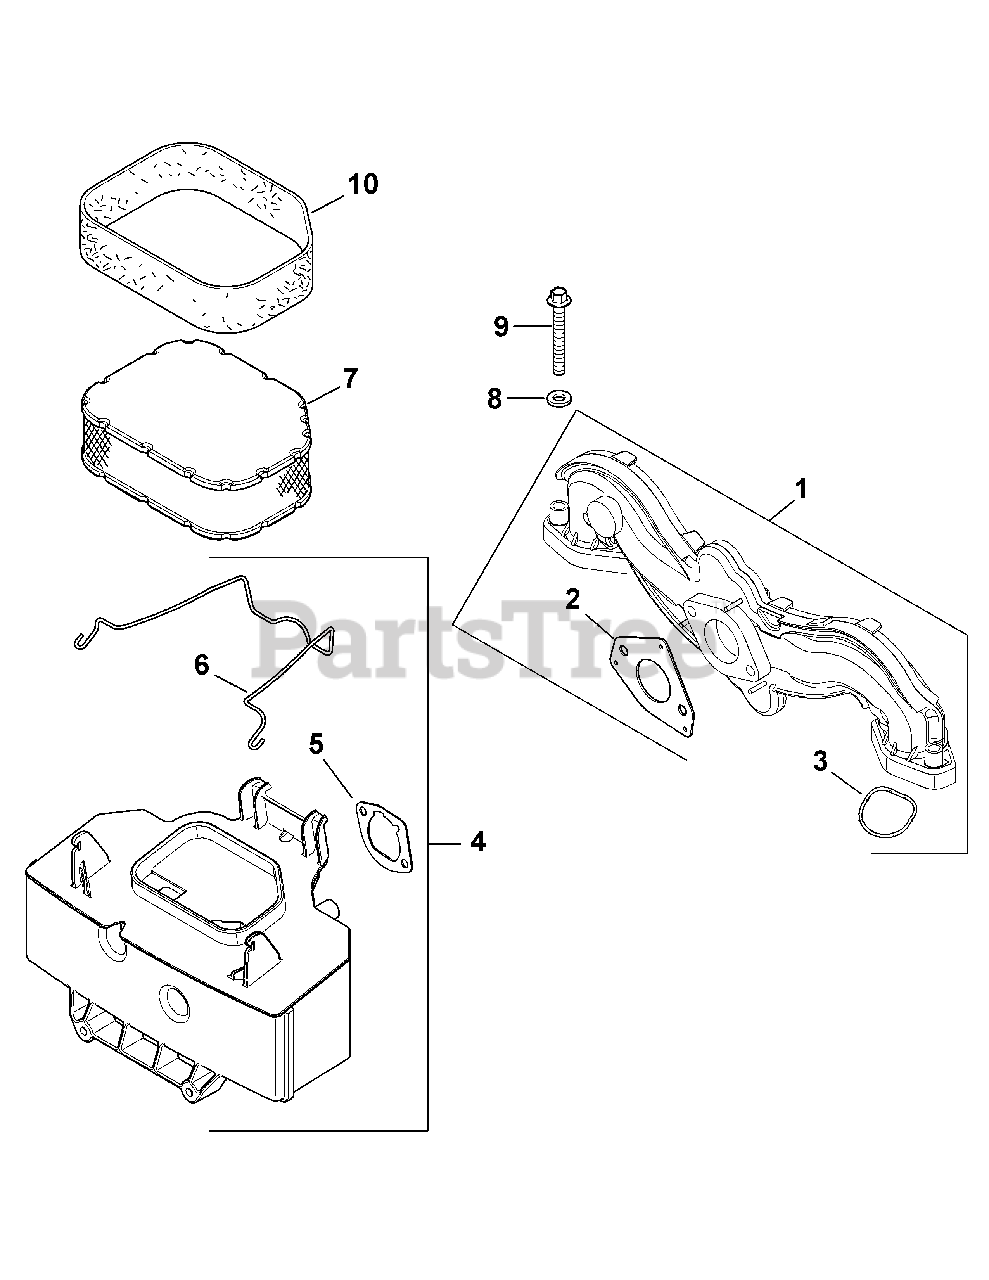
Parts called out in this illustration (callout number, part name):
1	Manifold, Intake
2	Gasket, Carburetor
3	O-Ring, Intake Port
4	Base, Air Cleaner w/Gasket, Latch
5	Gasket, Air Cleaner Base
6	Latch, Air Cleaner Element
7	Element, Air Filter
8	Washer, Flat, 1/4
9	Screw, Flange, M6 x 1.0 x 40
10	Pre-Cleaner, Element
